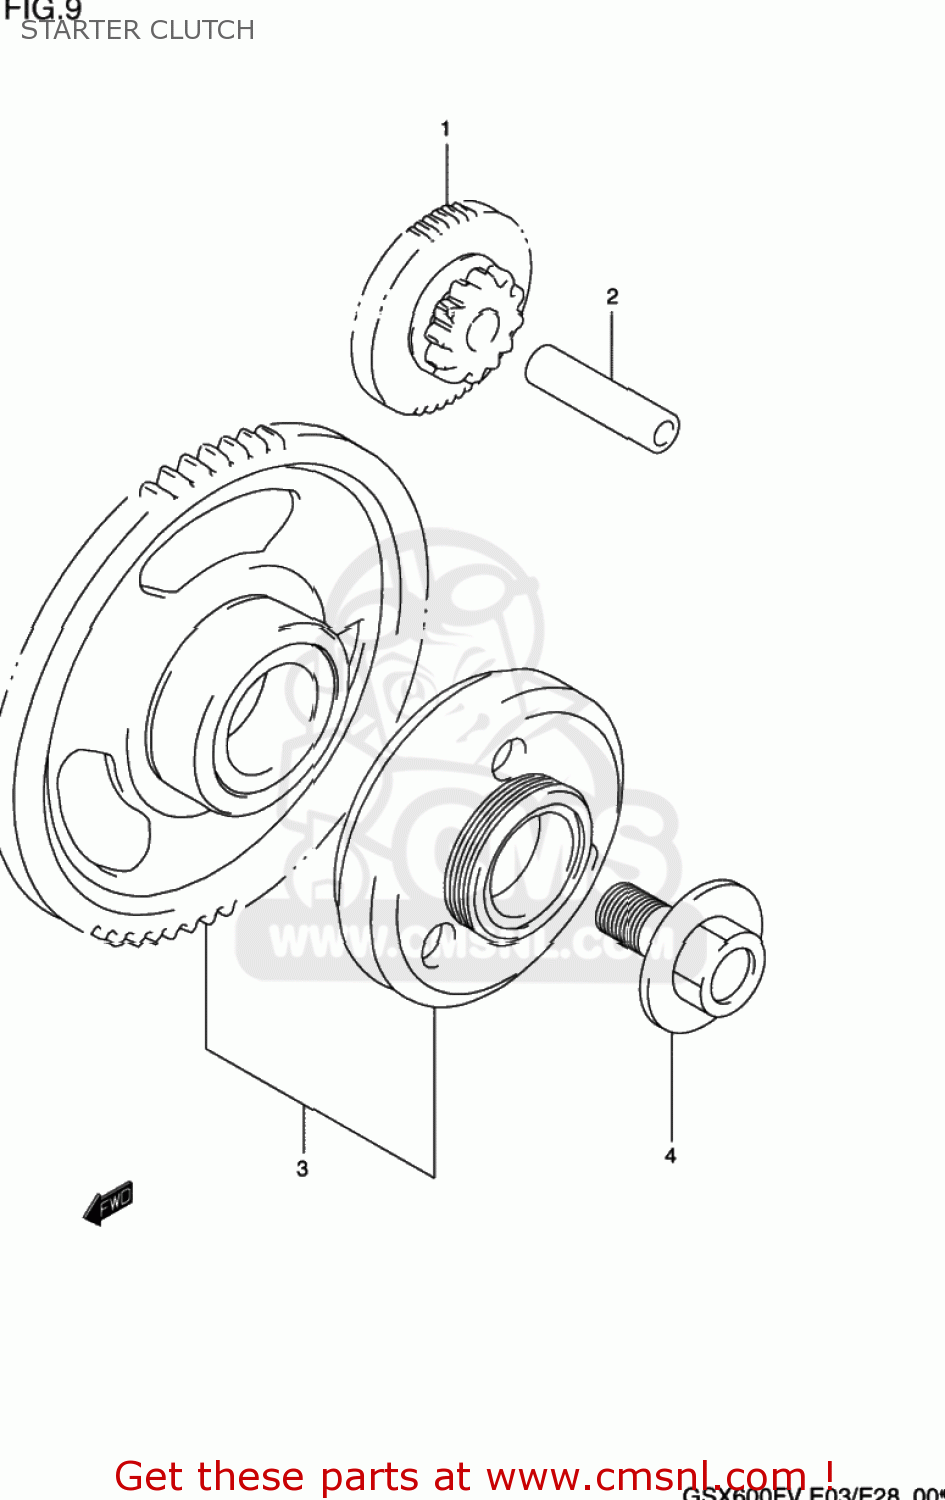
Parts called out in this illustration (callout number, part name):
1	GEAR,STARTER IDLE(NT:12,53)
2	PIN(7X11X42)
3	CLUTCH SET,STARTER
4	BOLT(14X21)
